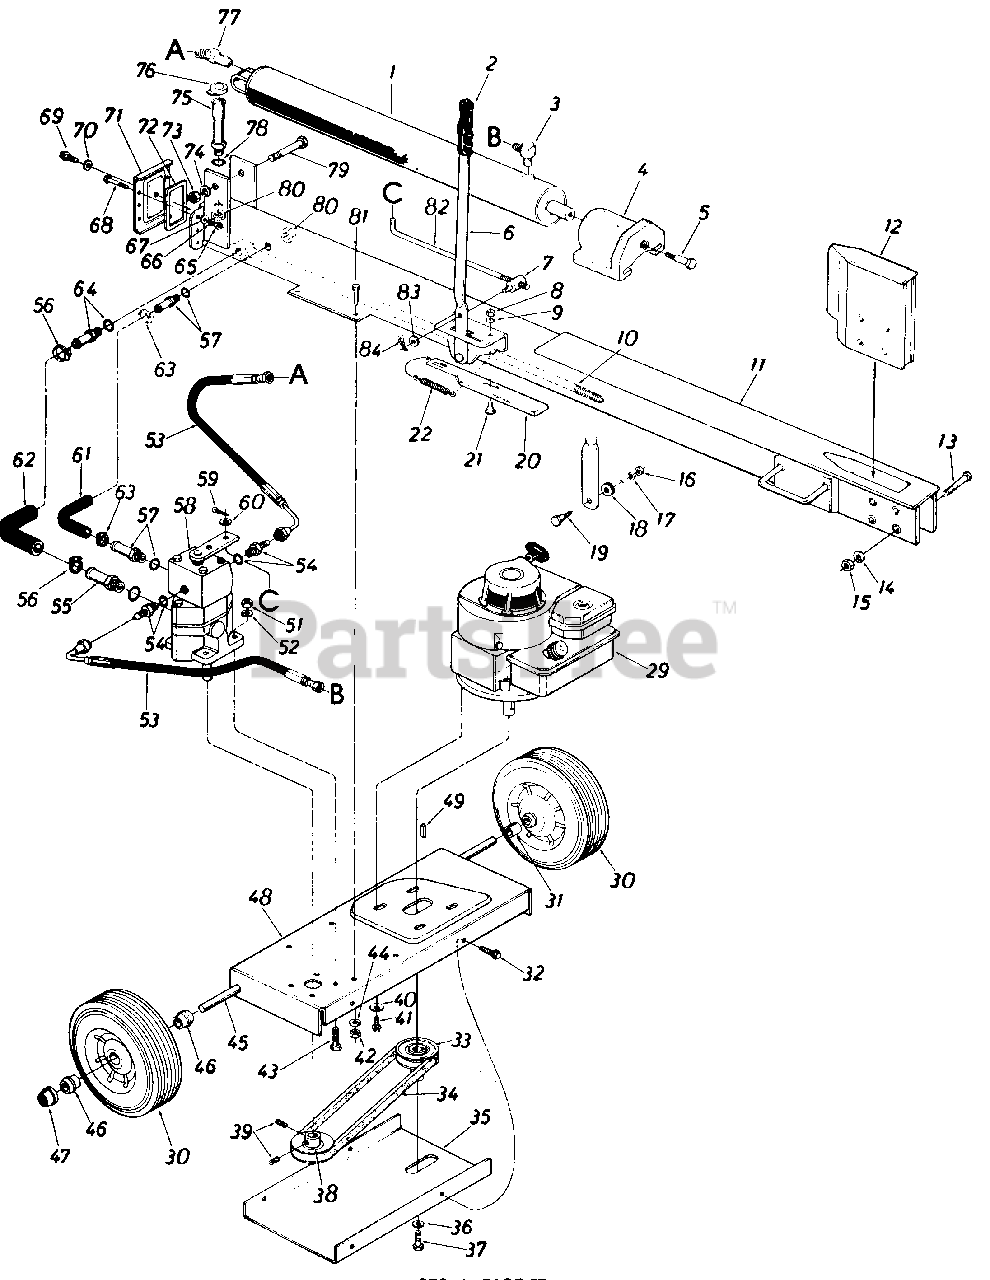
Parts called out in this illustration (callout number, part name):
1	2-1/2" Cylinder Ass'y. Compl.
2	Grip
3	90ø Elbow Adapter
4	Pusher Plate
5	ShouIder Bolt 5/8" Dia. x .660" Lg. 1/2-13 Thd.
6	Engagement Handle
7	Adjustment Ferrule
8	Hex Nut 5/16-18 Thd.*
9	L.-Wash. 5/16" I.D.*
10	Strainer Tube Ass'y.
11	Oil Tank Ass'y. Comp
12	Wedge Ass'y.
13	Hex Bolt 5/8-18 x 3.50" Lg. (Grade 5)
14	L.-Wash. 5/8" I.D.
15	Hex Nut 5/8-18 Thd.*
16	Hex Nut 3/8-16 Thd.*
17	L.-Wash. 3/8" I.D.*
18	Rubber Wash .
19	Shoulder Bolt .498x .340
20	Engagement Brkt.
21	Shoulder Bolt .437" Dia. x.180" Lg.
22	Extension Spring .50" O.D. x 4. 25" Lg.
29	Engine - B & S
30	Wheel Ass'y. Comp. 10.0" x 2.75
31	Sleeve .632" I.D. x .875" O.D. x.90" Lg.
32	Hex Wash. Hd. Self Tap. Scr. 1/4-20 x .50" Lg.
33	1/2" V-Pulley 7/8" I.D. x 7/8" I.D. x 3-1/4" O.D.
34	"V"-Belt (4L) 1/2" V x 30" Lg.
35	Belt Cover
36	L.-Wash. 5/16" I.D.*
37	Hex Bolt 3/8-24 x 1.0" Lg.*
38	1/2 (4L) "V"-Pulley 5/8" I.D. x 3-1/2 O.D.
39	Set Scr. 1/4-28 x .25" Lg.
40	Bell.-Wash..40" I.D. x .88" O.D.
41	Hex Wash. Hd. TT-Tap Scr. 3/8-16 x .87" Lg.
42	Hex Nut 5/16-2 Thd.*
43	Hex Bolt 5/16-18 x 1.00" Lg.*
44	L.-Wash. 5/16" I.D." I
45	AxleShaft 5/8"'Dia. x 25.5" Lg.
46	FlangeBrg.w/Flats.631" I.D.
47	Push Cap 5/8" Dia. Rod
48	Frame- Engine
49	Sq. Key 3/16" x 3/16" x 1.50" Lg.*
51	Hex Nut5/16-18 Thd.*
52	L.-Wash. 5/16" I.D.*
53	High Pressure Hose
54	Adapter - or Boss to MJIC 9/16-18 to 7/16-20
55	Adapter 3/4" Tubing to 3/4 -16 M-Boss
56	Hose Clamp 5/8" I.D.
57	Adapter 1/2" Tube 9/16-18 or M-Boss
58	Valve Ass'y.
59	Cotter Pin 3/32" Dia. x .75" Lg.*
60	Fl.-Wash. 344" I.D. x .62" O.D. x .063
61	Return Hose.50" I.D.
62	Suction Hose.75" I.D.
63	Hose Clamp 1/4" I.D.
64	Adapter 1.0" Tube 1-1/16-12 "O"-Ring
65	Hex Nut 5/16-18 Thd.*
66	L.-Wash. 5/16" I.D.*
67	Fl.-Wash. .343" 1. D. x .687" O.D. x .062
68	Hex Bolt 5/16-18 x 1.50" Lg.*
69	Hex Hd. Tap Scr. 5/16"
70	Gasket
71	End Plate
72	Gasket
73	Hex Nut 3/4" Thd.*
74	L.-Wash. 3/4" I.D.*
75	Filler Tube Ass'y.
76	Oil Fill Cap
77	45ø Male Adapter 7/16-20 MJ-1/4-18 NP
78	"O"-Ring .92" I.D. x 1.16" O.D. x .116 Dia.
79	Hex Bolt 3/4" x 4.0" Lg.
80	Hex Nut 11/16-12 Thd.
81	Hex Bolt 5/16-24 x 1.00" Lg. (Grade 5)
82	Engagement Rod 16.75" Lg.
83	Fl.-Wash. .344" I.D. x.62" O.D. x .063
84	HairPin Cotter 5/16" Dia.
